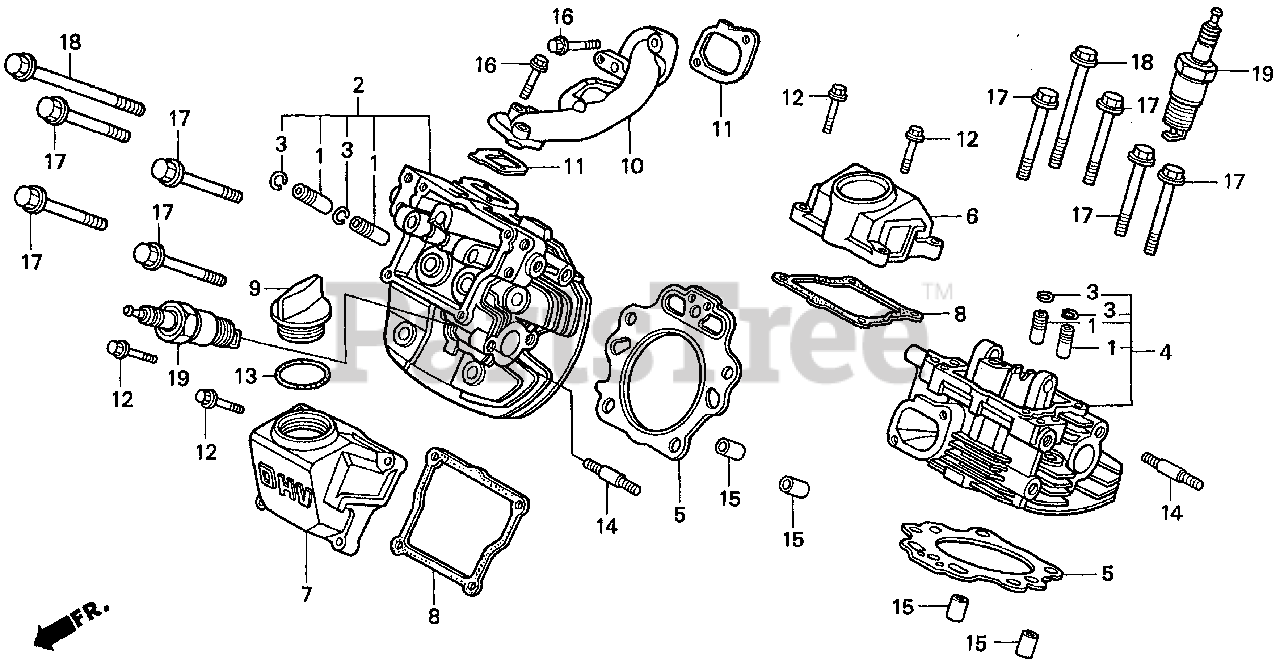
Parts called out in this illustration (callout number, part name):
1	GUIDE, EX. VALVE (OS)
2	CYLINDER HEAD, R.
3	CLIP, VALVE GUIDE
4	CYLINDER HEAD (#2)
5	GASKET, CYLINDER HEAD
6	COVER, HEAD
7	COVER, HEAD FILLER
8	GASKET, HEAD COVER
9	CAP, OIL
10	MANIFOLD, IN.
11	GASKET, IN. MANIFOLD
12	BOLT, FLANGE (6X25) (CT200)
13	O-RING (26X2.7)
14	BOLT, STUD (8X25)
15	PIN A, DOWEL (12X20)
16	BOLT, FLANGE (6X32)
17	BOLT, FLANGE (10X75)
18	BOLT, FLANGE (10X130)
19	SPARK PLUG (BPR2ES) (NGK)
19	SPARK PLUG (BPR4ES) (NGK)
19	SPARK PLUG (W14EPR-U) (DENSO)
19	SPARK PLUG (BPR6ES) (NGK)
